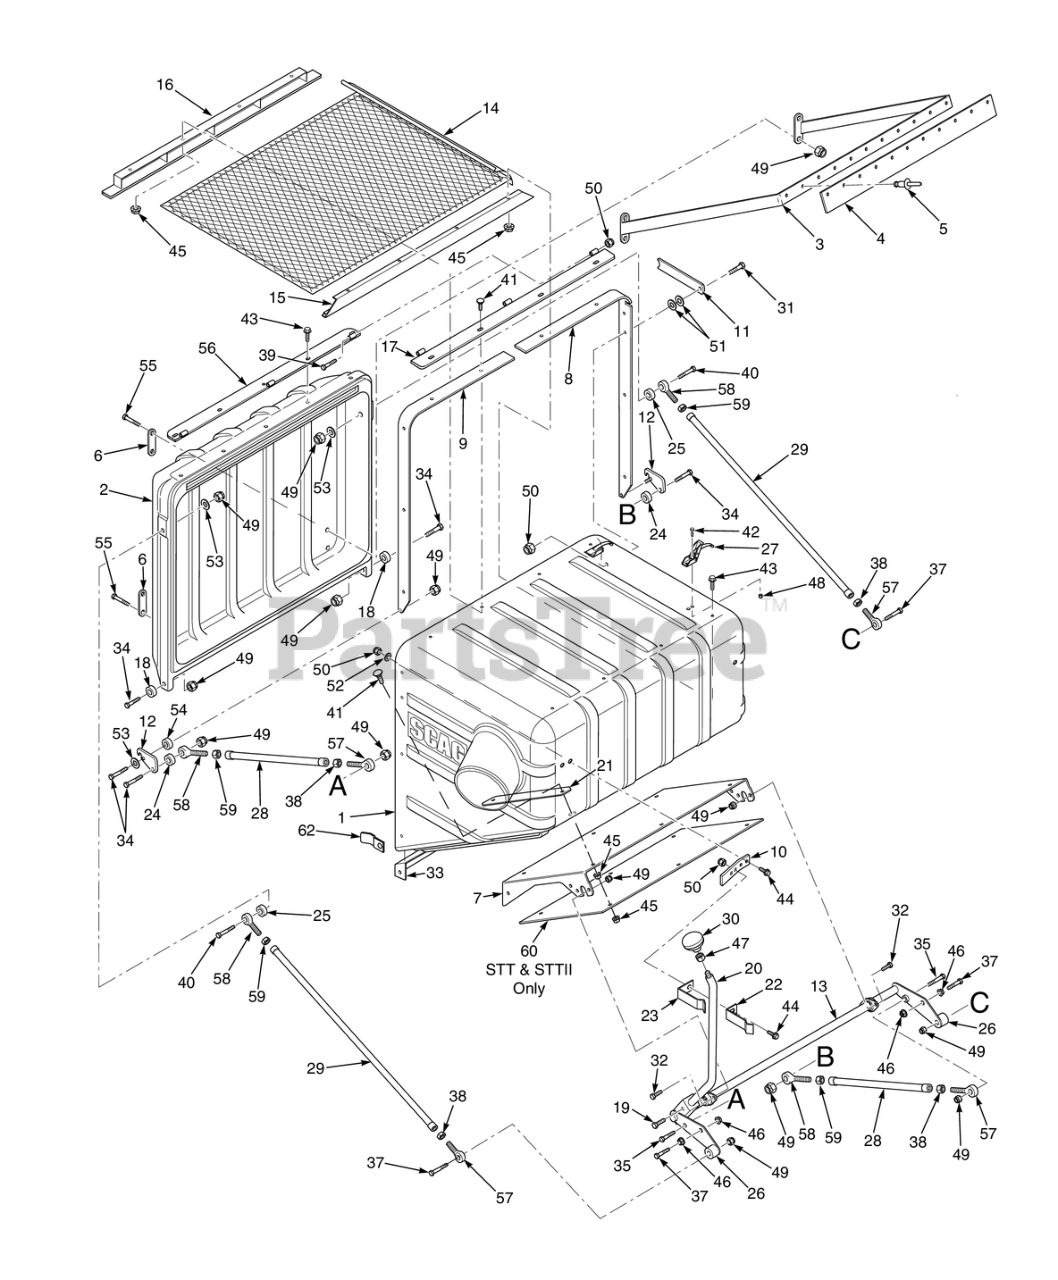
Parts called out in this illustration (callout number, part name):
1	Hopper, GC-STT-CS
2	Door, GC-CS
3	Sweeper Weldment, GC-CS
4	Pad, Rubber
5	Pop Rivet, 3/16 x .652"
6	Plate, Stiffener
7	Support Frame, Hopper
8	Hinge Bracket, L.H.
9	Hinge Bracket, R.H.
10	Mounting Bracket, Dump Handle Latch
11	Latch, Door Prop
12	Plate, Latch
13	Bellcrank Weldment, Upper
14	Debris Screen Weldment
15	Screen Support Weldment, Rear
16	Screen Support Weldment, Front
17	Hinge Weldment, Hopper
18	Spacer, Idler Bearing
19	Bolt, Hex Head 5/16-18 x 1-1/2" - Front
20	Rod, Dump Lever GC-SCZ-CS
21	Retainer Strip, Hopper
22	Latch, Dump Rod Inner
23	Latch, Dump Rod Outer
24	SPACER, IDLER
25	SPACER, J PULL ROD
26	SPACER, J-PULL ROD
27	LATCH, HOOD
28	Linkage Assembly, Lower
29	Linkage Assembly, Upper
30	Knob, Cutter Deck Release
31	Bolt, 5/16 - 18 x 1 - 1/4" Hex Head
32	Bolt, Hex Head, 3/8-16 x 3/4"
33	Bracket, Lower Stiffener
34	Bolt, Hex Head, 3/8-16 x 1-1/2"
35	Bolt, Hex Head 3/8-16 x 1-3/4" (Kohler EFI)
36	Alignment Bracket, GC-CS
37	Capscrew, Hex Head 3/8-16 x 2.0"
38	Nut, 3/8-24 UNF R.H. Thread
39	Bolt, Hex Head 5/16-18 x 3-1/2"
40	Bolt, Hex Head, 3/8-16 x 3-1/2"
41	Bolt, Carriage 5/16-18x1" (large frame units only)
42	SCREW, PHILLIPS WASHER HEAD #10-32 X 1/2"
43	Capscrew, 5/16-18 x .75 Serrated Flange Hex Head
44	Cpscrw, 5/16-18 x 1"Serrated Flange Hex Head
45	Nut, Serrated Flange 5/16-18 (Right Front Engine Mounting, Briggs and Kohler Only)
46	NUT, 3/8-16 SERRATED FLANGE HEX HEAD
47	HEX NUT, JAM 3/8-16
48	HEX NUT, ELASTIC STOP LOCK # 10-32
49	HEX NUT, ELASTIC STOP LOCK, 3/8-16
50	HEX NUT, ELASTIC STOP LOCK, 5/16-18
51	Socket Head Capscrew #8-32 x 1/2"
52	Flatwasher, 5/16-.375 x .875 x .083 (35BV & 37BV-EFI)
53	Flatwasher, 3/8" Special (.391 x .938 x .105)
54	Bushing, Hopper Latch GC-CS
55	Bolt, Hex Head 3/8-16 x 3" - 52"
56	Hinge Weldment, Door
57	Rod End Male, 3/8-24 R.H. Thread
58	Rod End Male, 3/8-24 L.H. Thread
59	Nut, 3/8-24 UNF-2B LH Thread
60	Heat Shield, GC-STT Only
